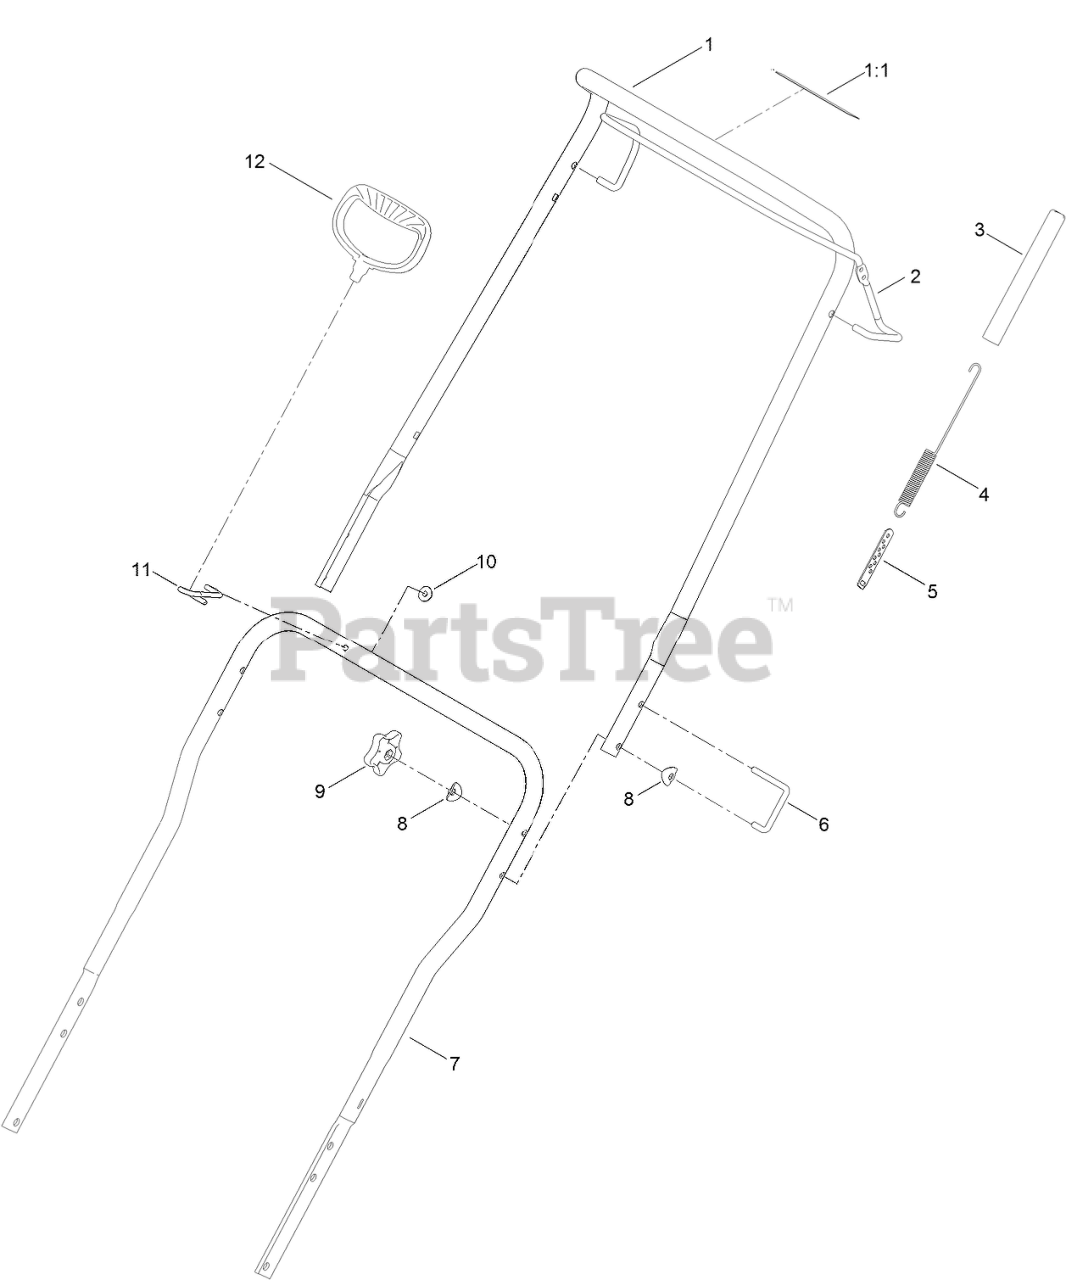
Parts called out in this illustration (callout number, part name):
1	UPPER HANDLE ASM
1:1	DECAL-DRIVE, ROTOR
2	BAIL-CONTROL
3	COVER-SPRING
4	SPRING-EXTENSION, CLUTCH
5	ADJUSTER-CLUTCH CABLE
6	LOCK-HANDLE
7	HANDLE-LOWER
8	WASHER
9	KNOB-HANDLE
10	NUT-HF
11	GUIDE-ROPE
12	HANDLE-RECOIL
